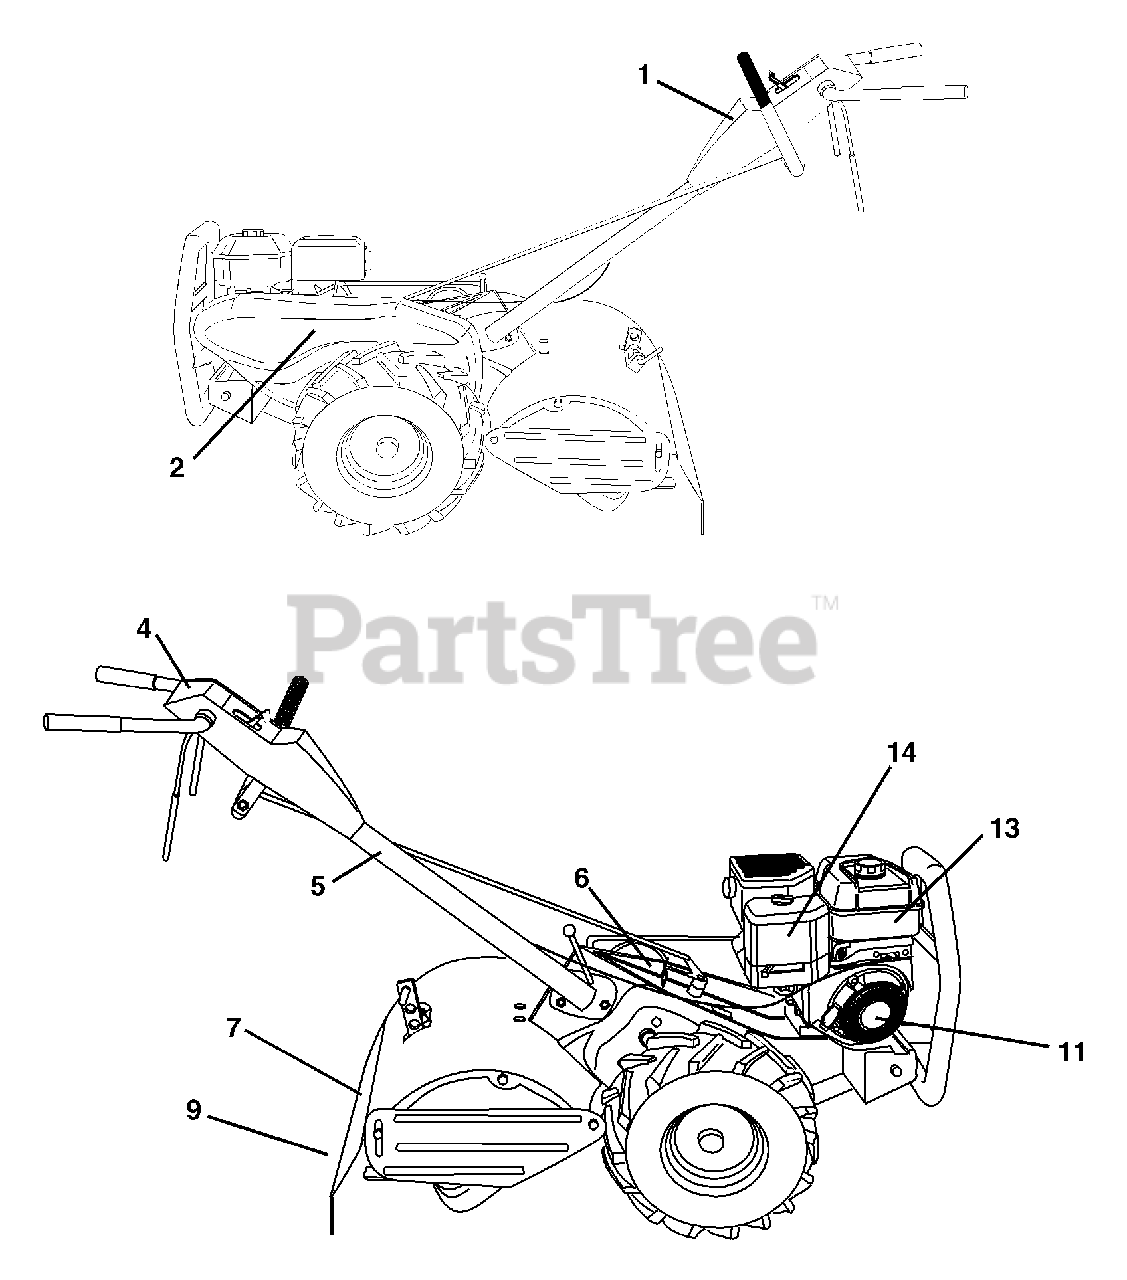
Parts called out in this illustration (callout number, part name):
1	Decal, CNTRL PNL
2	Decal, Decal, Blt Grd
4	Decal, Instruction, Tilling
5	Decal, Hand Placement
6	Decal, Shift Indicator
7	Decal, caution
9	Decal, Warning, Rotating Tines
11	Decal, Rewind
13	Decal, B&S Tank
14	Decal, B&S Air Cleaner
